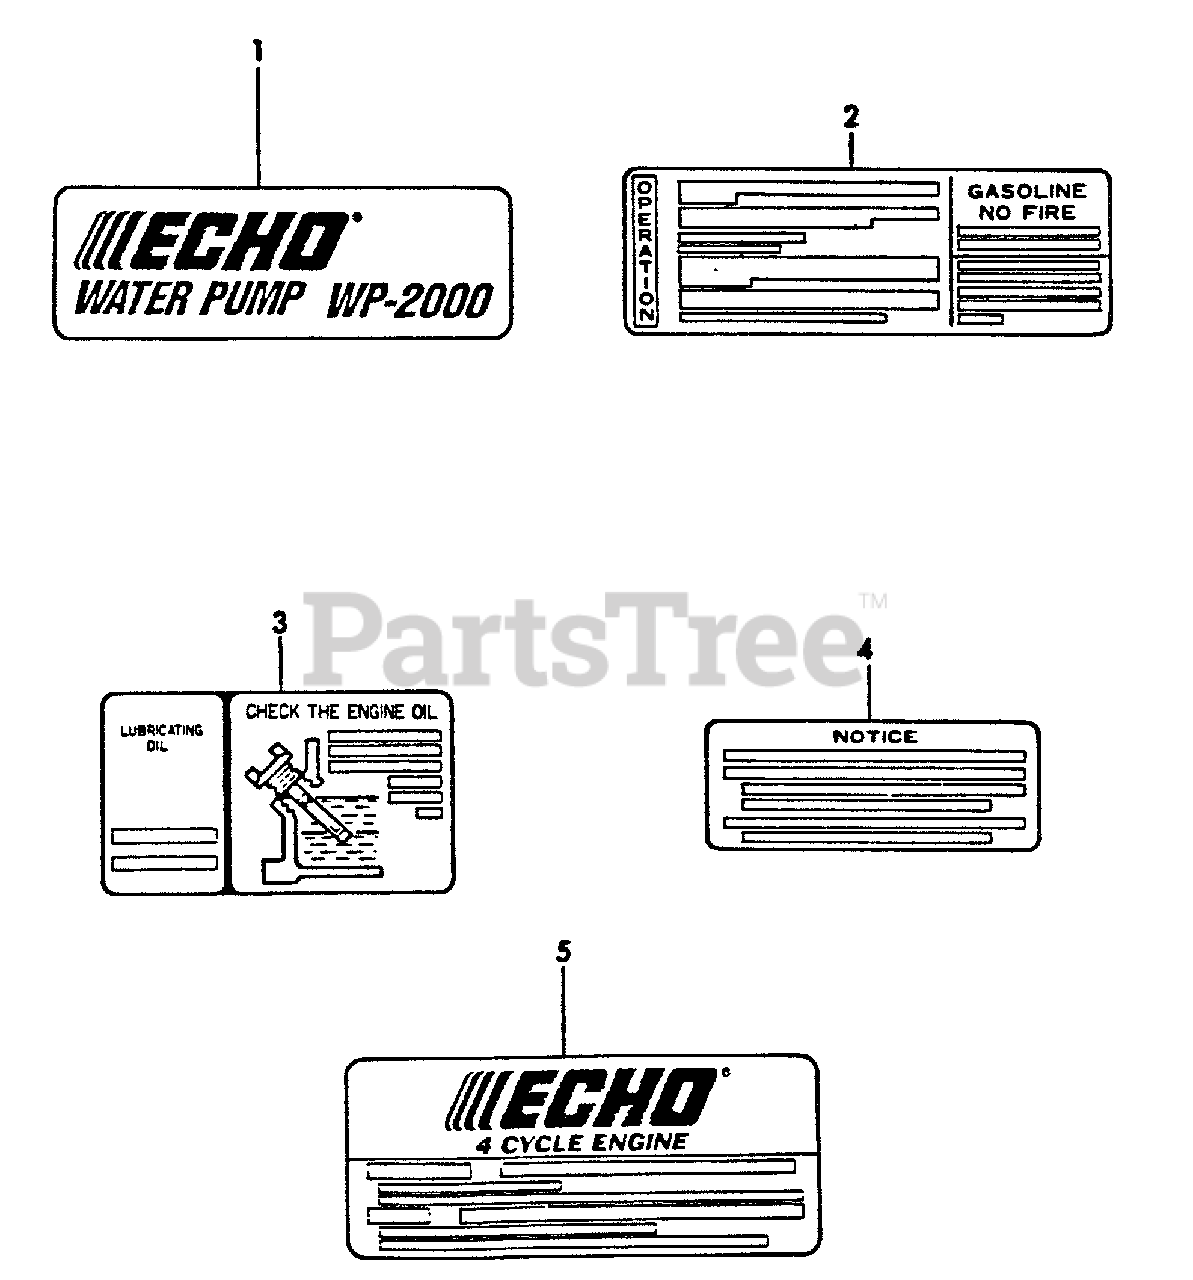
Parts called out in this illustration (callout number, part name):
1	LABEL - MODEL WP2000
2	LABEL - OPERATION
3	LABEL - OIL
4	LABEL - AIR CLEANER
5	LABEL - ECHO
